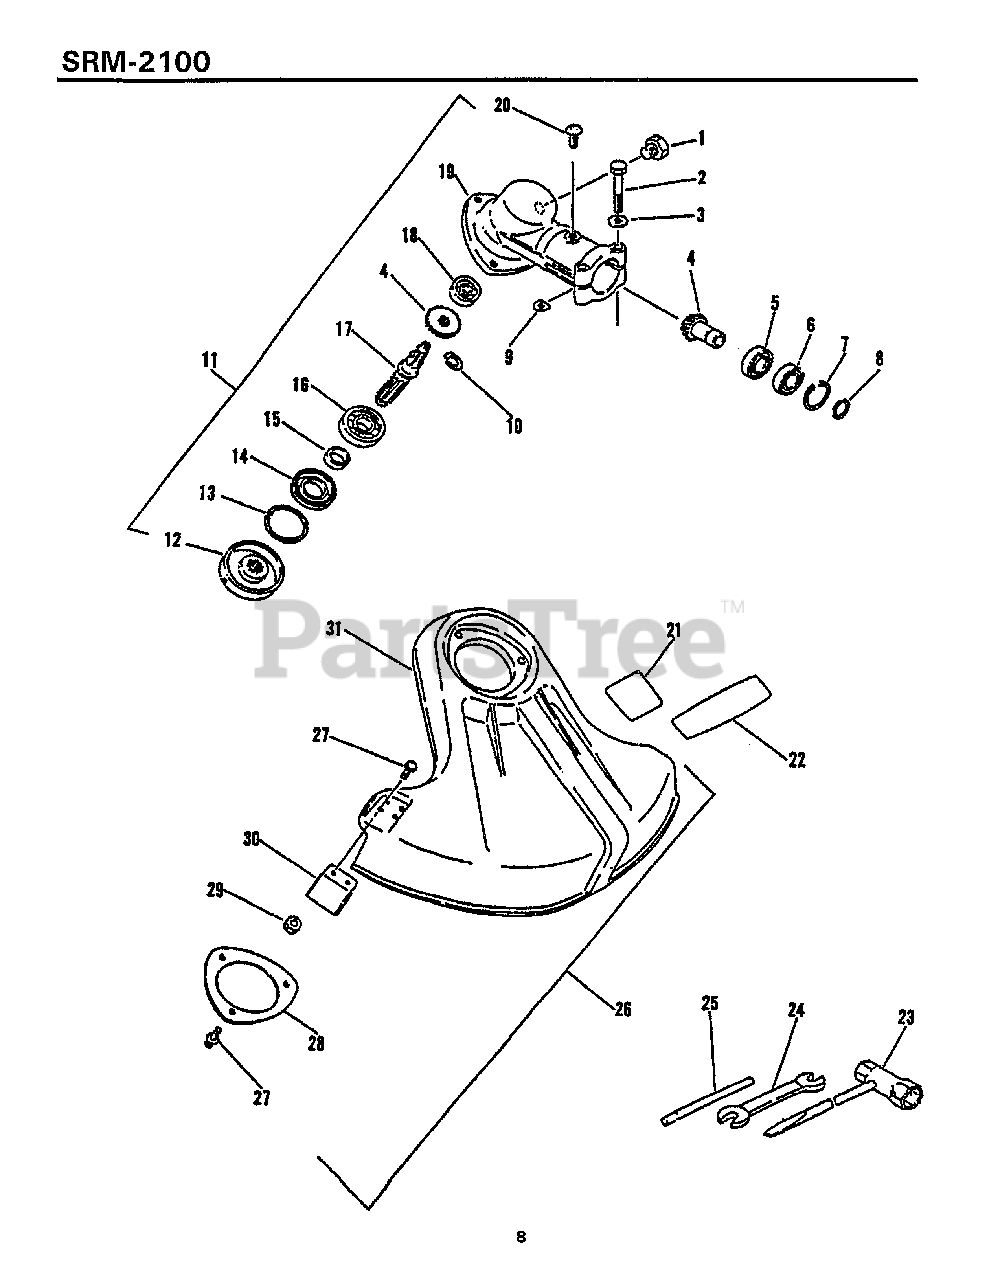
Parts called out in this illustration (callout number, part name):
1	Bolt 8x8
2	Bolt 5x35
3	Washer 5
4	Gear Set, Bevel
5	Bearing, Ball 6900
6	Bearing, Ball 6900
7	Circlip 22
8	Circlip 12
9	Washer, Shim
10	Circlip 10
11	Housing Asy, Gear
12	Plate, Adapter (U)
13	Circlip 32
16	Bearing, Ball 6201
17	Shaft, P.T.O.
18	Bearing, Ball 609
19	Housing, Gear
20	Screw 5x10
21	Lable, Caution
22	Lable, Echo
23	Wrench, W/Screwdriver
24	Spanner 8x10
25	Locking Tool
26	Shield Asy
27	Screw 5x16
28	Bracket, Shield
30	Knife, Cord
31	Shield, Blade
